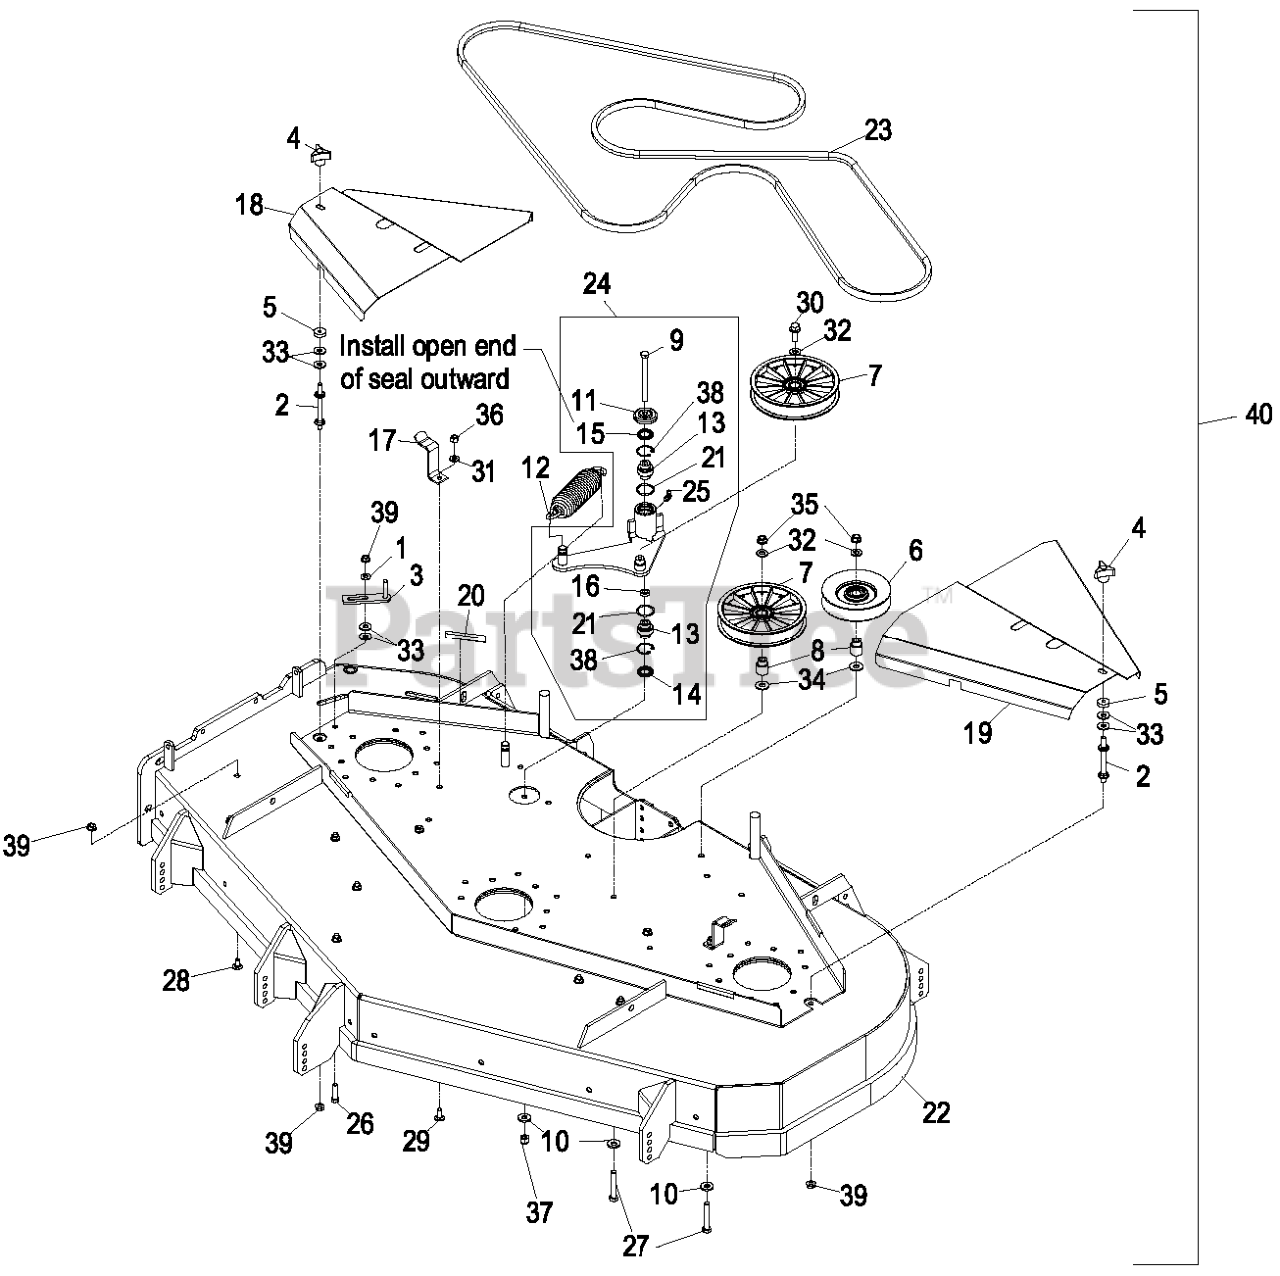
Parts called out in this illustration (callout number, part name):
1	WASHER-SPRING
2	STUD-SHIELD, BELT (SHORT)
3	GUIDE-BELT
4	KNOB-3 PRONG
6	PULLEY-IDLER
7	PULLEY,IDLER 6"
8	BUSHING-IDLER
9	SCREW-HH
10	WASHER-BELLEVILLE
11	GUARD-TOP
13	BEARING-SPHERICAL
14	SEAL-LIP, DOUBLE
15	SEAL-LIP, SINGLE
17	LATCH,BELT SHIELD
18	SHIELD, BELT RH 605 W/DEC
19	SHIELD, BELT LH 605 W/DEC
20	STRIP-SEAL
22	ASM, DECK 605 W/DECALS
23	BELT,BLADE DRIVE
24	KIT, IDLER ARM W/BEARINGS
25	FITTING-GREASE, 90 DEG
26	SCREW-HH
27	SCREW-HH
28	SCREW-CARR
29	SCREW-CARR
30	SCREW-HHF
31	WASHER-PLAIN
32	WASHER-FLAT
33	WASHER-FLAT
34	WASHER-FLAT
35	NUT-HHF, WHIZ
36	NUT-LOCK, NI
37	NUT-LOCK, NI
38	RING-SNAP
40	Asm, Deck Complete 60"
